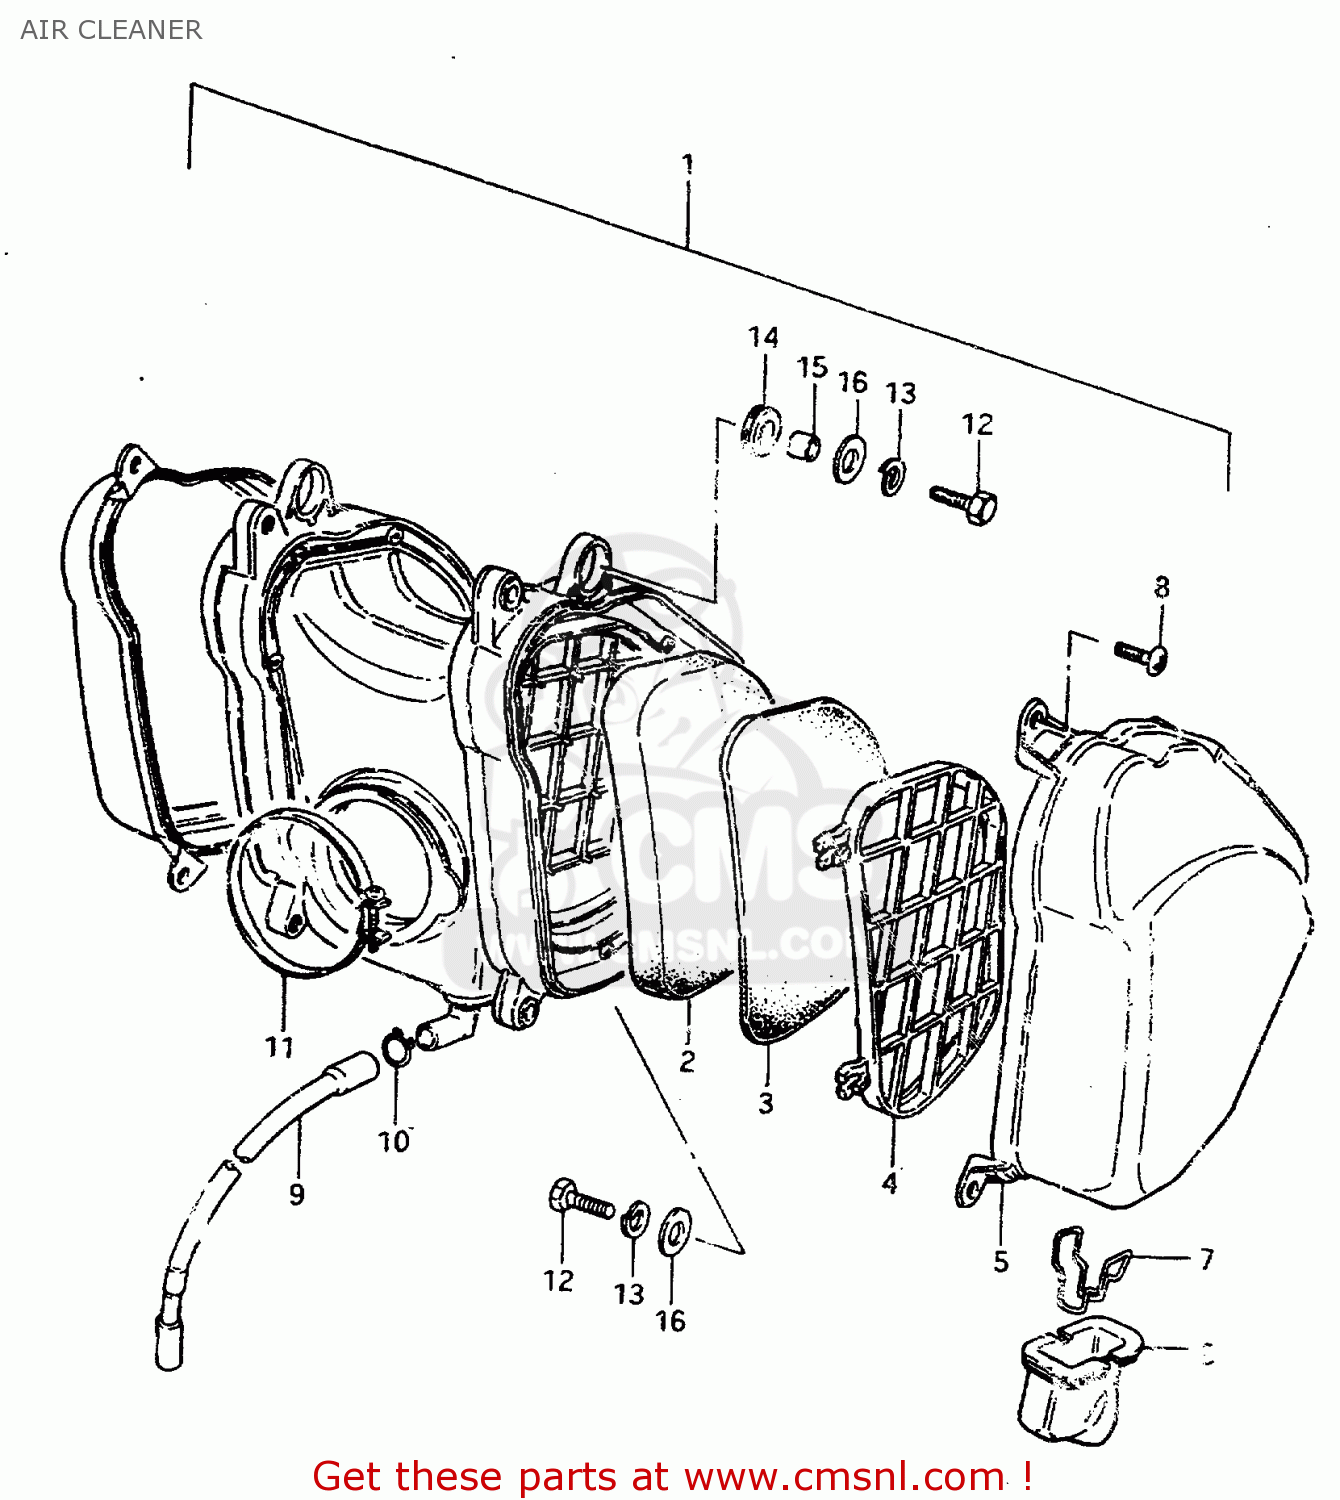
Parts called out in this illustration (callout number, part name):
1	CLEANER ASSEMBLY,AIR
2	FILTER
3	FILTER,2ND
4	HOLDER,AIR CLEANER,LEFT
5	CAP,AIR CLEANER,LEFT
6	DRAIN TUBE
7	DRAIN STOPPER
8	SCREW
9	DRAIN TUBE
10	CLIP
11	CLAMP
12	BOLT
13	WASHER,LOCK
14	CUSHION
15	SPACER (7X9X7)
16	WASHER(6.5X20X1.6)
